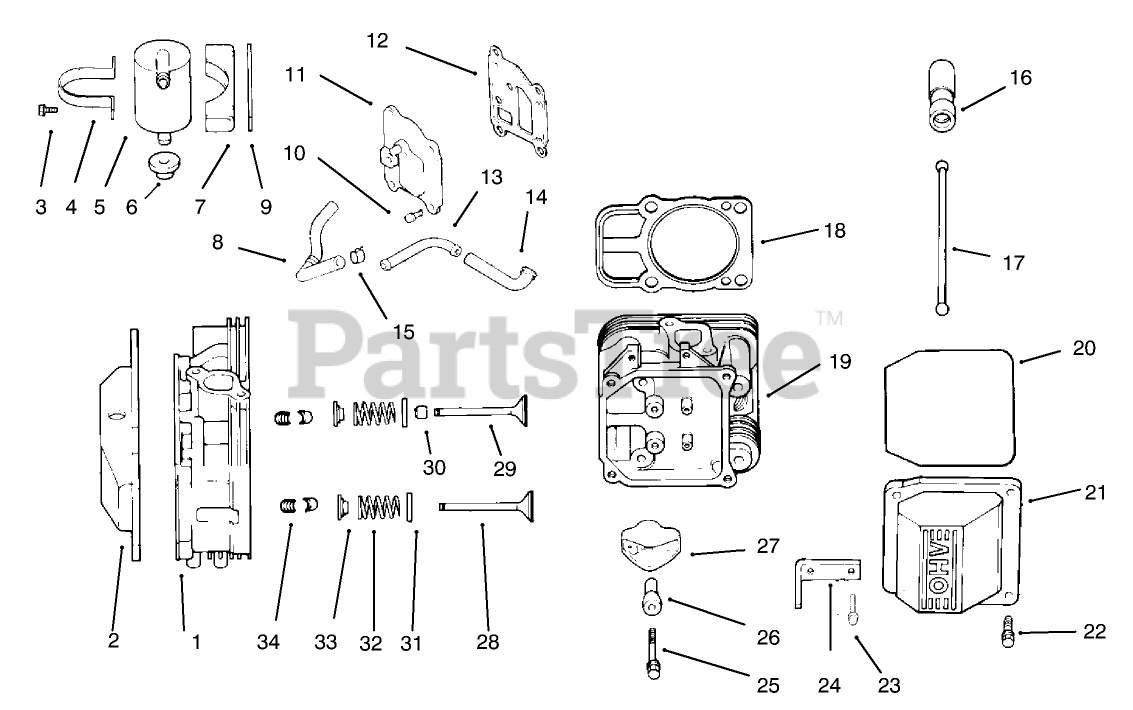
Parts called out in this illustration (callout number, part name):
1	Head ASM-#1 Cylinder (Only On: 72103, 72083)
2	Kit-Valve Incl 6 20-22
3	Screw M5x0.8x16 (Only On: 72042, 72063, 72062, 72043)
4	Strap-Lifting
5	Kit-Breather Incl 3-9
6	Grommet-Rubber (Only On: 72103)
7	Bracket
8	Hose-Breather
9	Spacer
10	Screw
11	Cover-Breather (Only On: 72103)
12	Gasket-Breather
13	Fitting
14	Hose-Breather
15	Clamp
16	Lifter-Valve
17	Rod-Push
18	Gasket-Cylinder Head
19	Head ASM-#2 Cylinder (Only On: 72103, 72083)
20	O-Ring
21	Kit-Valve Cover (Incl. Ref. #2 3)
22	Screw-Shoulder
23	Screw
24	Strap-Lifting
25	Screw
26	Pivot-Arm, Rocker
27	Arm-Rocker
28	Valve-Exhaust
28	Valve-Exhaust (.25)
29	Valve-Intake
29	Valve-Intake (.25)
30	Seal-Valve Stem
31	Retainer-Spring
32	Spring-Valve
33	Cap-Valve Spring
34	Kit-Retainer
